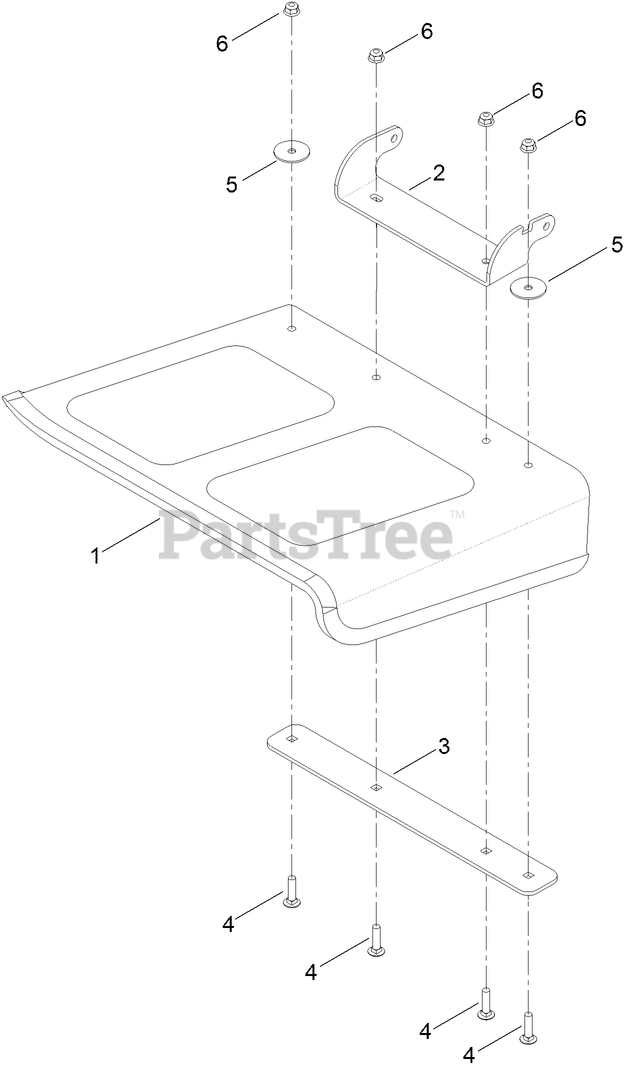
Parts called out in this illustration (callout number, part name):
1	DEFLECTOR
2	BRACKET-DEFLECTOR, UPPER
3	PLATE-DEFLECTOR
4	SCREW-CARR
5	WASHER-FLAT
6	NUT-HF, NI
